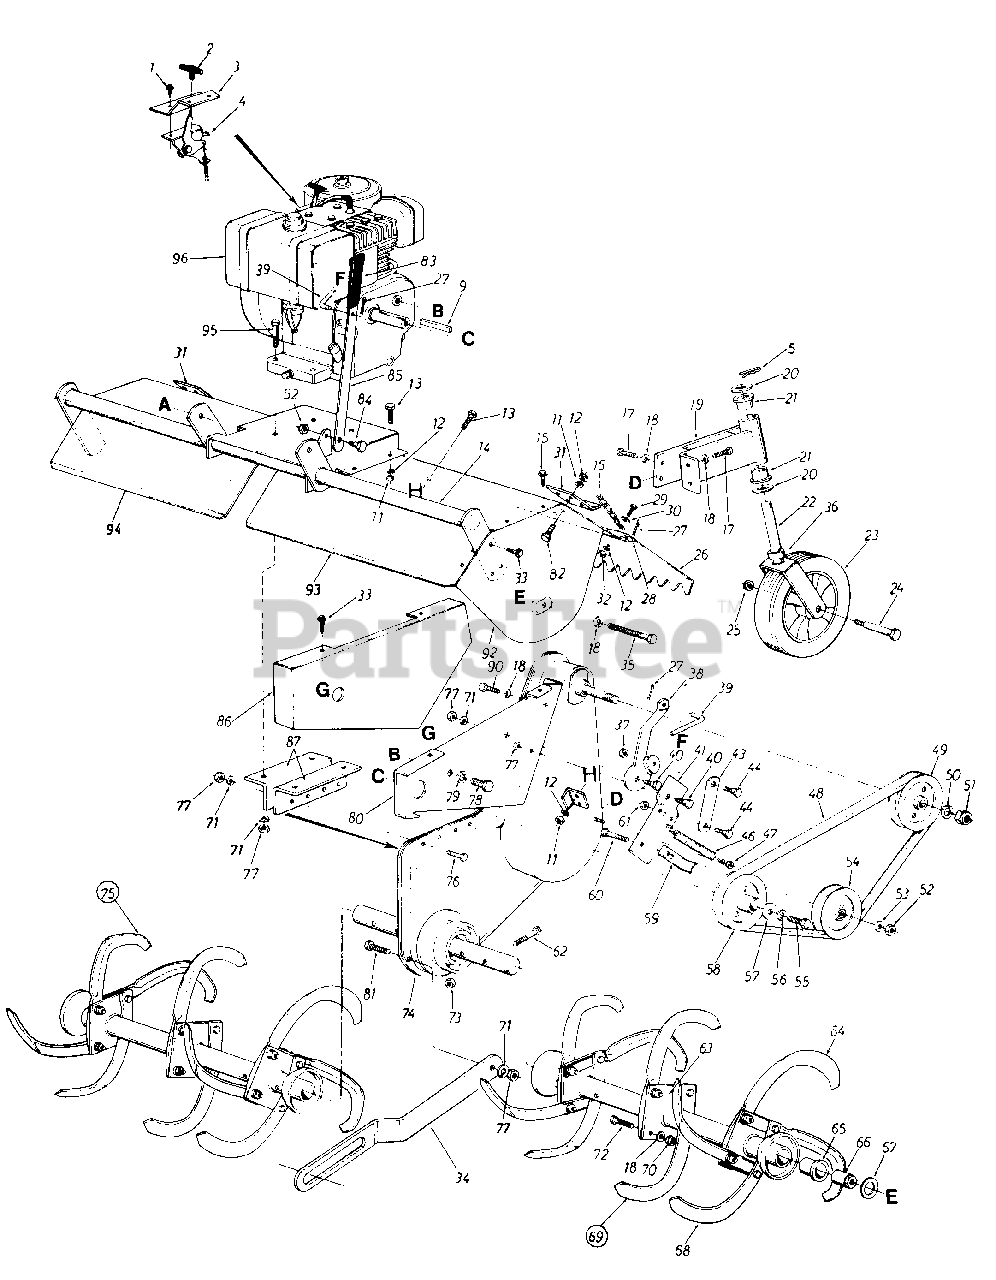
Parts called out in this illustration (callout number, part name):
1	Hex Wash. Hd. Self-Tap Scr. #8 x .50" Lg.
2	Throttle Control Knob- (Service Only)
3	Throttle Control Bracket
4	Throttle Control Ass y. Comp.
5	Internal Cotter Pin
11	Hex Nut 1/4-28 Thd.
12	L-Wash. 1/4" I.D.*
13	Hex Bolt 1/4-28 x .62" Lg.*
16	#2 Dog Chain x 20" Lg. (2 Req'd.)
17	Hex Bolt 3/8-24 x .75" Lg.*
18	L-Wash. 3/8" I.D.*
21	Flange Bearing 3/4" I.D. x 1.00" O.D.
22	Swivel Wheel Caster
23	Wheel Assembly 10.0 x 2.75
24	Shoulder Bolt .623" I.D. x 3.62" Lg.
25	Hex Cent. L-Nut 7/16-14 Thd.
28	L.H. Flap Rod
29	Hex Bolt 1/4-20 x .62" Lg.
30	Fl-Wash. 1/4" I.D.
33	Hex Wash. Hd. Self-Tap Scr. 1/4" x.62" Lg.
35	Hex Bolt 3/8-16 x 1.25" Lg.
36	Spacer .752" I.D. x 1.25" O.D.
37	Hex Cent. L-Nut 5/16-18 Thd.
40	Shoulder Bolt 7/16" Dia. x 1.75" Lg.
46	Extension Spring .62 O.D. x 6.12" Lg.
47	Hex Crown Nut 3/8-24 Thd.
48	"V"-Belt 1/2" X 43" Lg. (Kevlar)
49	1/2" "V"-Pulley 4.75" O.D. x .625" Bore
50	L-Wash. 5/8" I.D.*
51	Hex Ins. L-Nut 5/8-18 Thd.
52	Hex Cent. L-Nut 3/8-16 Thd.
53	Fl-Wash. 3/8" I.D.
54	Idler Pulley 4.0" O.D.
56	L-Wash 7/16" I.D.*
57	Fl-Wash. 7/16" I.D. x 1.38" O.D.
58	1/2" "V"-Pulley .475" O.D. x 1.00" Bore
61	Hex Cent. L-Nut 5/16-18 Thd.
62	Hex Bolt 7/16-14 x 2.00" Lg.
65	Flange Bearing 1.00" I.D.
67	Thrust Wash. 1/2" I.D. x 1.55" O.D.
69	Tine Assembly Comp.-L. H .
70	Hex Nut 3/8-24 Thd.*
71	L-Wash. 5/16" I.D.*
72	Hex Bolt 3/8-24 x 1.50" Lg.*
73	Hex Cent. L-Nut 7/16-14 Thd.
77	Hex Nut 5/16-18 Thd.*
78	Hex Bolt 1/2-20 x .88" Lg. (Grade 5)
79	L-Wash. 1/2" I.D.*
80	Clutch Support Bracket
82	Hex Bolt 1/4-28 x .75" Lg.*
83	Plastic Grip
84	Shoulder Bolt .498 Dia. x .212 Lg.
85	Clutch Handle
90	Hex Bolt 3/8-16 x .62" Lg
96	8 H.P. Engine
